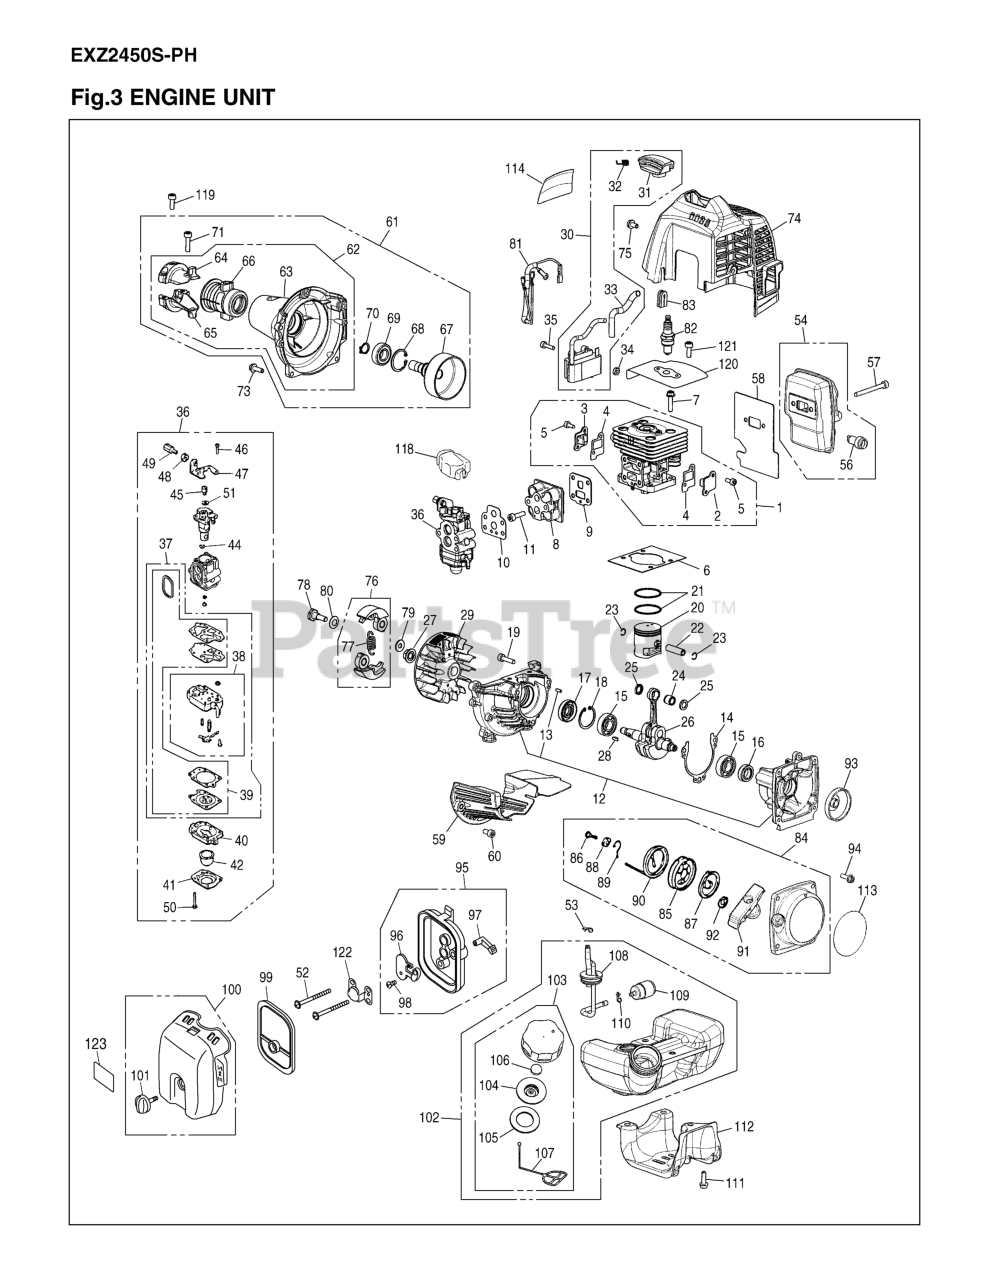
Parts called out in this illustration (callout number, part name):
1	CYLINDER-C
2	COVER, TR-S
3	COVER, TR-F
4	GASKET, TR
5	BOLT
6	GASKET, BASE
7	BOLT
8	INSULATOR
9	GASKET
10	GASKET, CARB
11	BOLT, TORX
12	CRANKCASE-C
13	PIN
14	GASKET, CASE
15	BEARING
16	SEAL
17	SEAL, OIL (RPLS 1140-21220)
18	RING, SNAP, M28 x 1.2
19	BOLT (RPLS 2850-14220)
20	PISTON
21	RING, PISTON
22	PIN, PISTON
23	RING, SNAP (RPLS 1101-41320)
24	BEARING
25	WASHER
26	CRANKSHAFT-C
28	KEY
29	ROTOR
30	COIL-A
31	CAP
32	SPRING
33	TUBE
34	SPACER (RPLS -71260)
35	BOLT TORX
36	CARBURETOR ASSY
37	REBUILD KIT
38	BODY, PUMP
39	GASKET KIT
40	BODY, PURGE
41	COVER, PUMP
42	PUMP, PRIMING
44	RING
45	SWIVEL
46	SCREW
48	NUT, CABLE ADJUSTER
49	SCREW, CABLE ADJUSTER
50	SCREW
51	WASHER
52	BOLT TORX
53	CLIP
54	MUFFLER ASSY
56	ARRESTER
57	BOLT
58	GASKET, MUFFLER
59	PLATE
60	BOLT
61	HOUSING ASSY (RPLS T1551-31000
62	HOUSING COMP (RPLS. -31110)
64	BRACKET (A) (RPLS -31211)
65	BRACKET (B)
66	CUSHION (RPLS -31231)
67	DRUM (REPLACES 4810-31122)
68	RING, SNAP, M28 x 1.2
69	BEARING
70	RING, SNAP (RPLS 3130-13270)
71	BOLT (RPLS 2850-14220)
73	BOLT
74	COVER, ENGINE
75	BOLT (RPLS. T4950-51011)
76	SHOE COMP
77	SPRING
78	BOLT
79	WASHER, FLAT (USE 182303)
80	WASHER (RPLS -51241)
81	CORD COMP.
82	SPARK PLUG
83	GROMMET
84	RECOIL-A
85	REEL
86	SCREW
87	SPRING, SPIRAL
88	COLLAR
89	ARM
90	ROPE (REPLACES 4500-75160)
91	KNOB (RPLS -75420)
92	PLATE, STOPPER
93	PULLEY
94	BOLT, TORX
95	CLEANER BODY ASSY
96	PLATE, CHOKE
97	LEVER
98	SCREW
99	ELEMENT
100	CLEANER COVER ASSY
101	CLEANER KNOB
102	TANK ASSY
103	CAP ASSY (RPLS -85201)
104	HOLDER (REPLACES -85230)
105	PACKING
106	FILTER
107	STOPPER
109	FUEL FILTER (BLK SLEEVE)
110	CLIP (REPLACES 2841-31280)
111	BOLT
112	GUARD, TANK
113	LABEL, RECOIL
114	LABEL, EMISSION
118	COVER
119	BOLT
120	PLATE
121	BOLT
